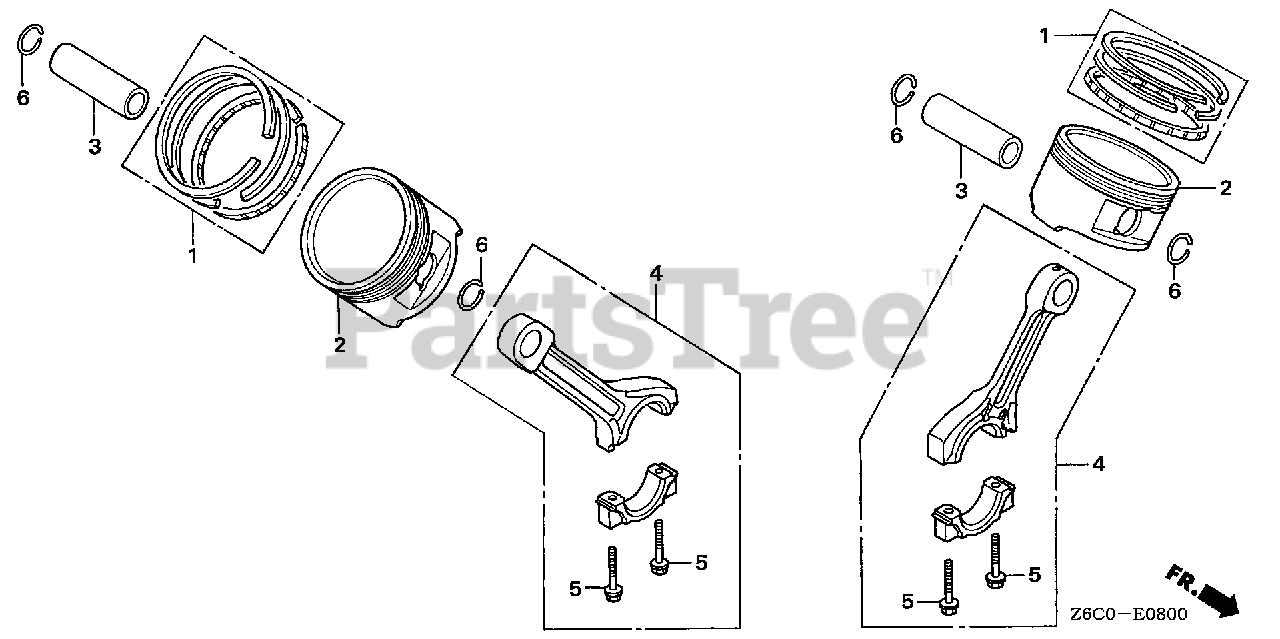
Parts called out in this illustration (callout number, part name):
1	RING SET, PISTON (STD) (NIPPON)
1	RING SET, PISTON (STD) (TPR)
1	RING SET, PISTON (0.25) (NIPPON)
1	RING SET, PISTON (0.25) (TPR)
1	RING SET, PISTON (0.50) (NIPPON)
1	RING SET, PISTON (0.50) (TPR)
1	RING SET, PISTON (0.75) (NIPPON)
1	RING SET, PISTON (0.75) (TPR)
2	PISTON (STD)
2	PISTON (0.25)
2	PISTON (0.50)
2	PISTON (0.75)
3	PIN, PISTON
4	ROD ASSY., CONNECTING
5	BOLT, CONNECTING ROD (6X37)
6	CLIP, PISTON PIN (18MM)
